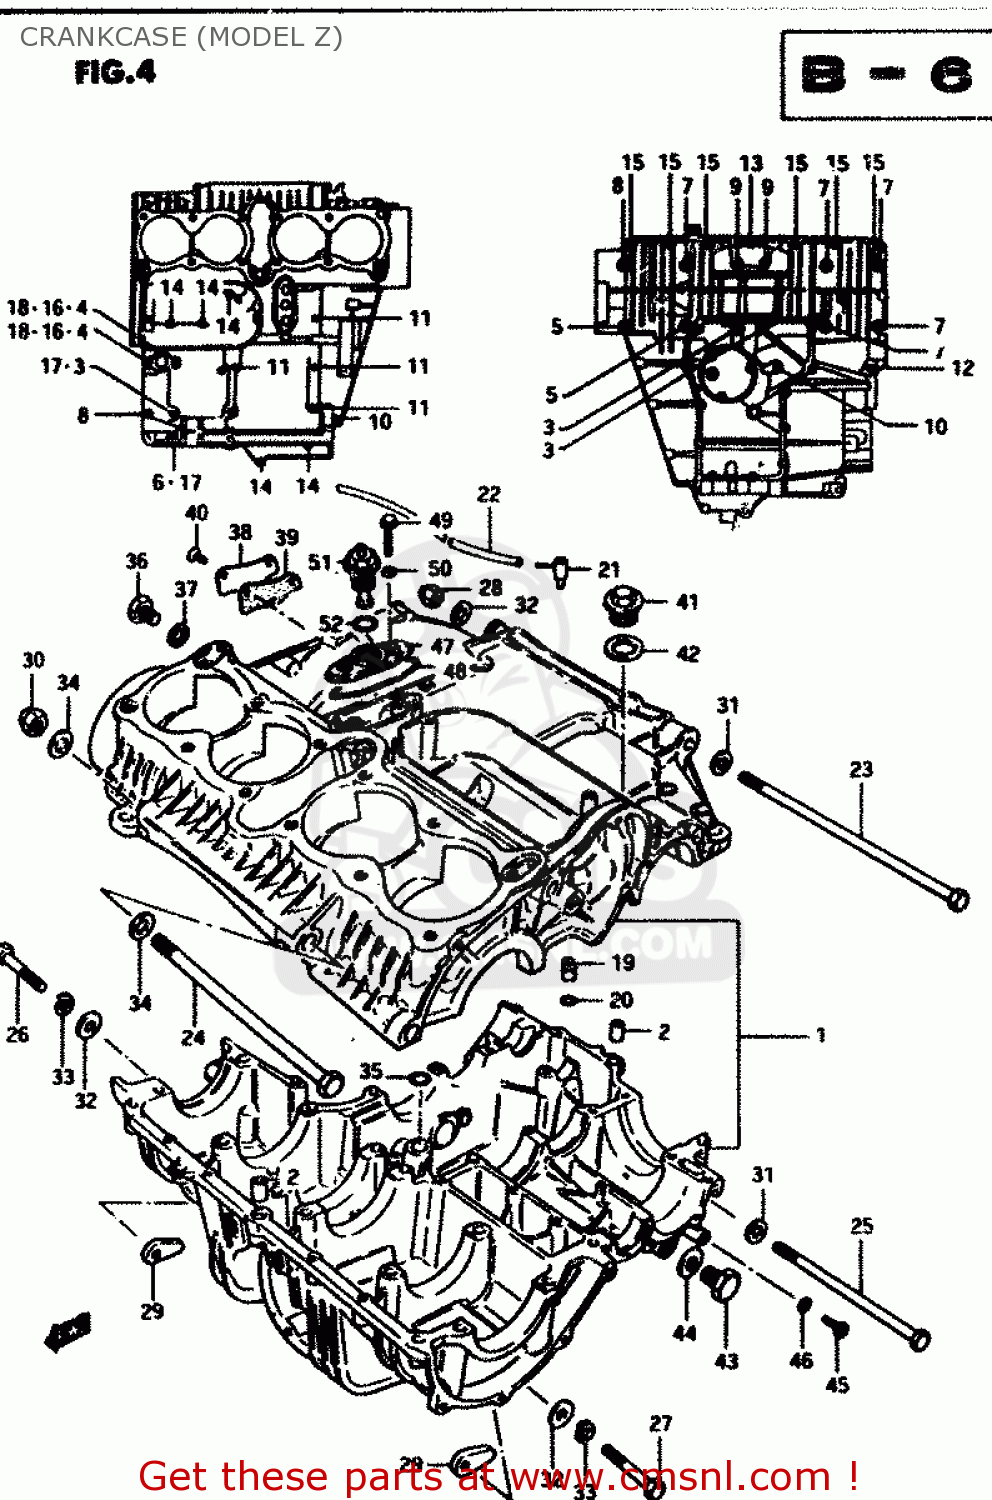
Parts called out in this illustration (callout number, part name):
2	PIN
3	BOLT
4	BOLT
5	BOLT
6	BOLT
7	BOLT 8X90
8	BOLT 8X65
9	BOLT
10	BOLT (6X90)
11	BOLT (6X75)
12	BOLT
13	BOLT ,6X50
14	BOLT,UNDER
15	BOLT 6X35
16	NUT
17	NUT
18	GASKET 8.2X14X1 (NAS)
19	UNION
20	O RING(D:1.05,ID:3.1)
21	BPLUG,BEVEL GEAR BREATHER
22	HOSE
23	BOLT 10X270
24	SHAFT,REAR SWING ARM
25	BOLT(10X165)
26	BOLT 10X60
27	BOLT (10X50)
28	NUT
29	NUT
30	NUT 12MM
31	WASHER(10.5X20X3.2)
32	WASHER
33	LOCK WASHER
34	WASHER
35	O RING(D:3.2,ID:12.9)
36	PLUG (14X12)
37	GASKET(14X19.2X2) (NAS)
38	CAP,OIL GALLERY
39	GASKET,OIL GALLERY (MCA)
40	SCREW
41	PLUG
42	GASKET
43	PLUG
44	GASKET(14X19.2X2) (NAS)
45	SCREW(6X10)
46	GASKET (NAS)
47	HOUSING,OIL PRESSURE SWITCH
48	O RING,PRESSURE SWITCH HOUSING
49	BOLT
50	GASKET (NAS)
51	SWITCH ASSEMBLY
52	O RING(D:1.9,ID:18.8)
